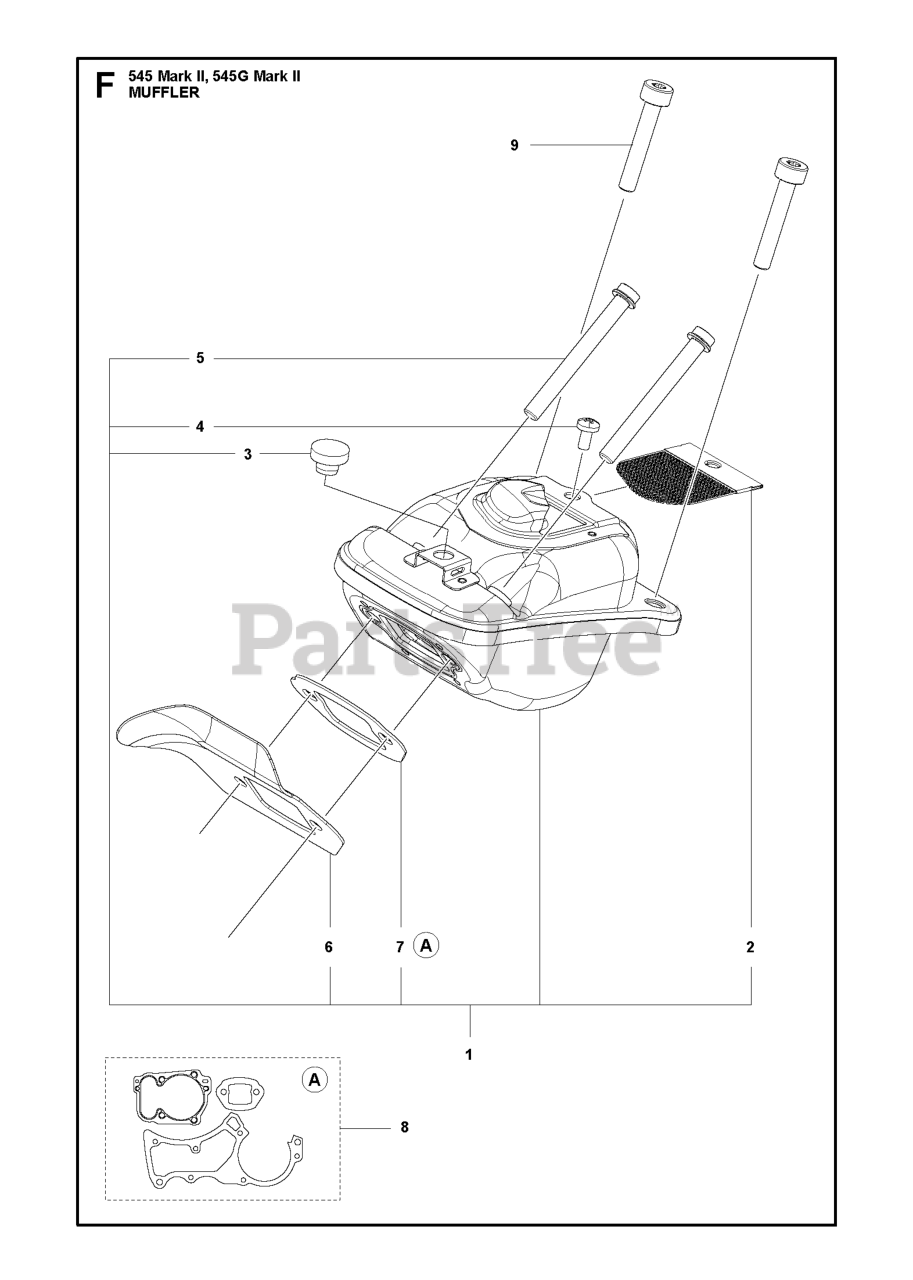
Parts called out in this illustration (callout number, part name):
1	MUFFLER KIT MUFFLER KIT
2	SPARK ARRESTER
3	RUBBER BUMPER
5	SCREW ITXSCM HEXABOULAR SOCKET
6	HEAT DEFLECTOR
7	MUFFLER GASKET
8	GASKET KIT MARK II
